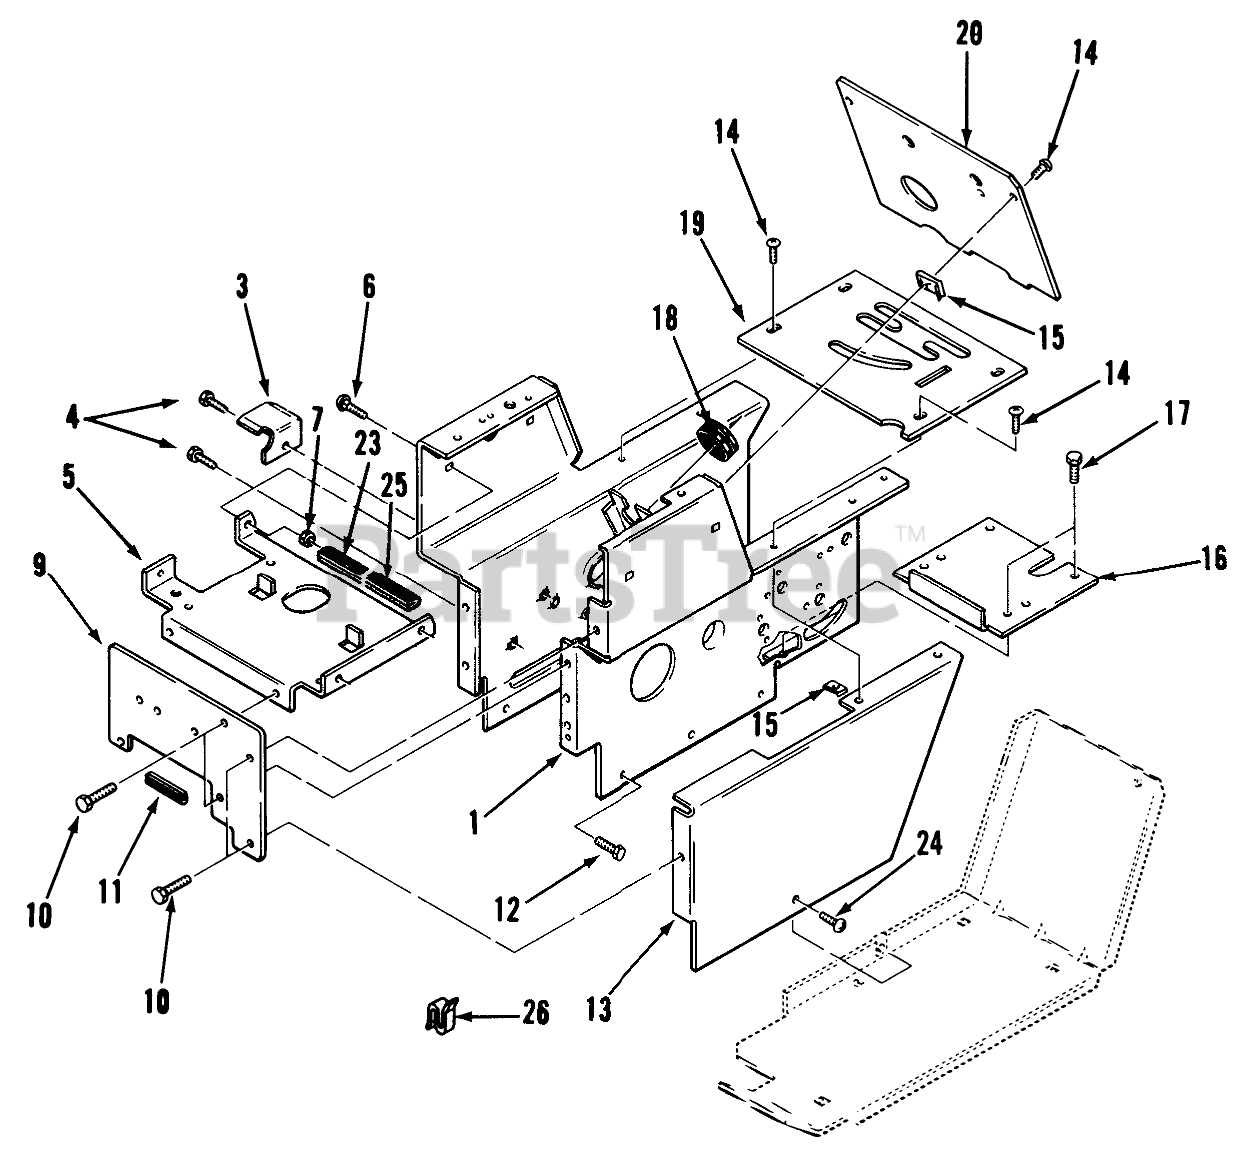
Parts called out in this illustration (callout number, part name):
1	Hoodstand
3	Belt Bracket
4	SCREW
5	SUPORT-BATERYB
6	BOLT CARR. 5/16X1/2 BK
7	Nut
9	Front Plate
10	SCREW
11	EDGE TRIM 4IN OF 102896
12	SCREW
13	Cover-Side LH
14	SCREW-PPH
16	Cover-Dust
17	SCREW
18	GROMMET
19	PLATE-SHIFT B
20	Plate-Hood Stand
23	EDGE TRIM 5" OF 102896
24	Screw
25	EDGE TRIM 2" 102896
26	SPEED CLIP
